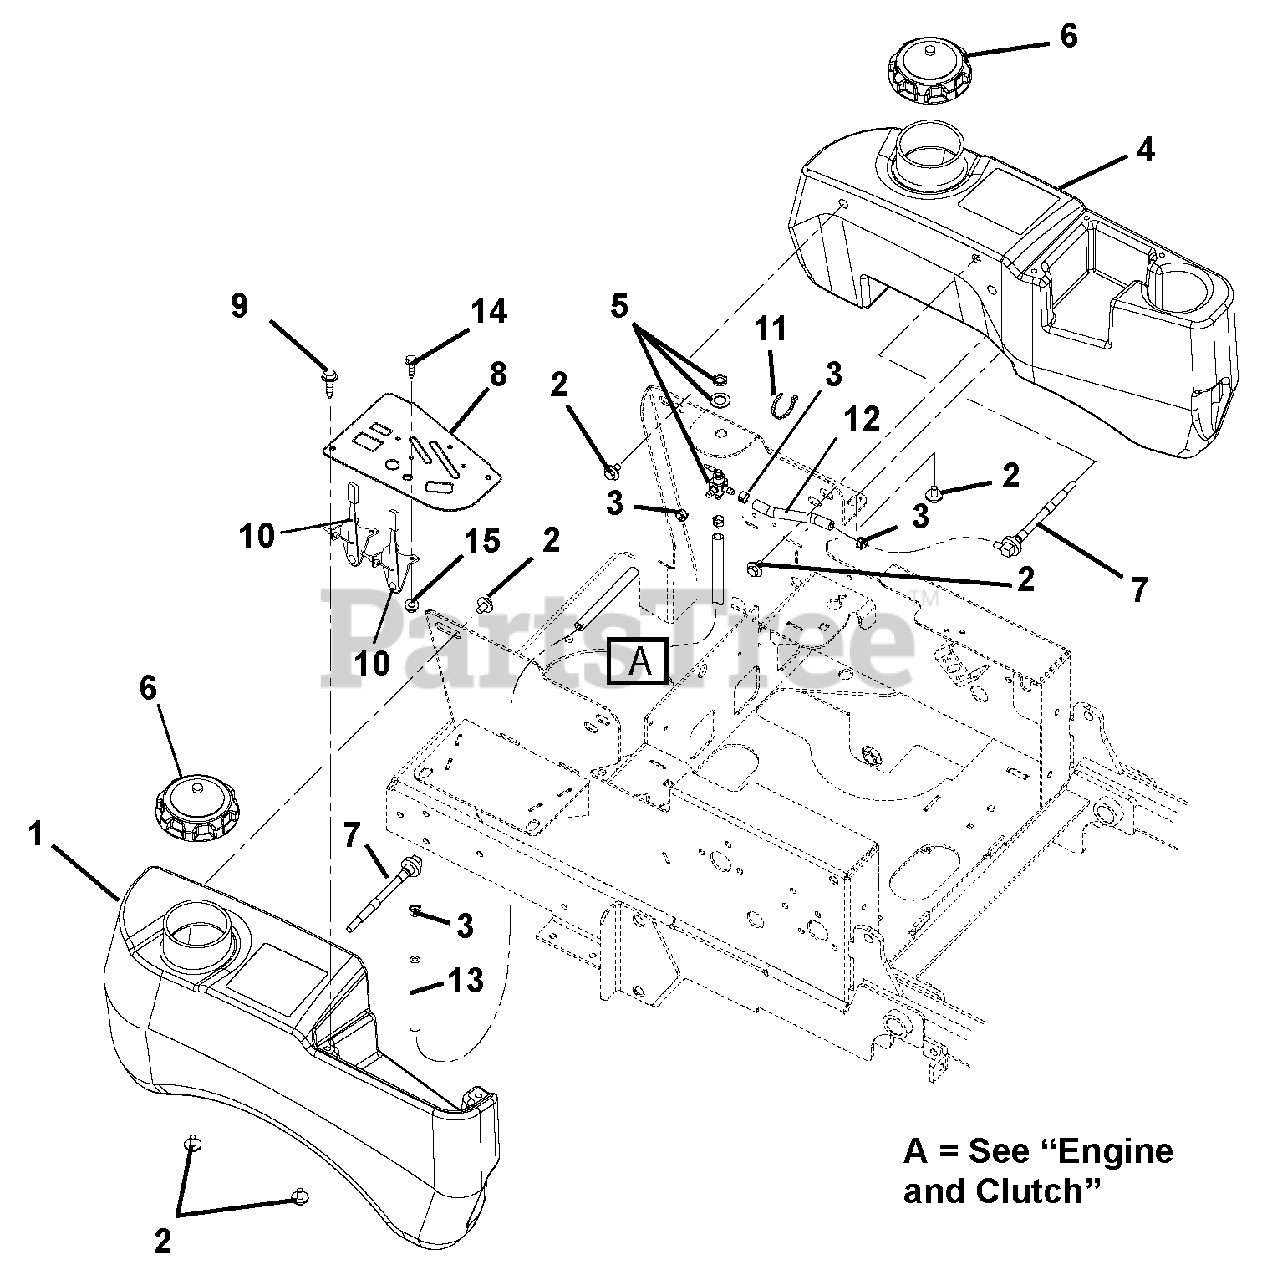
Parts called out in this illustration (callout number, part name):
1	TANK,RH FUEL,HD
2	BOLT, SEMS .31-18 X .62
3	CLAMP, FUEL LINE
4	TANK,LH FUEL,HD
5	VALVE, FUEL
6	CAP, FUEL
7	ASS'Y, SMALL TANK FUEL PICK-UP
8	PANEL - CONTROL
9	SCR-MCH 10-24X.38 HWHSTAINLESS
10	CABLE, CONTROL
11	CABLE TIE LG 5-1/2
12	1 INCH OF HOSE, .25 LOW-PERM BULK GAS
13	1 INCH OF HOSE, .25 LOW-PERM BULK GAS
14	@SCR-MCH 10-24X.50 HWH YWZC
15	@NUT-LK-NYL 10-24 W/INSRT YWZC
